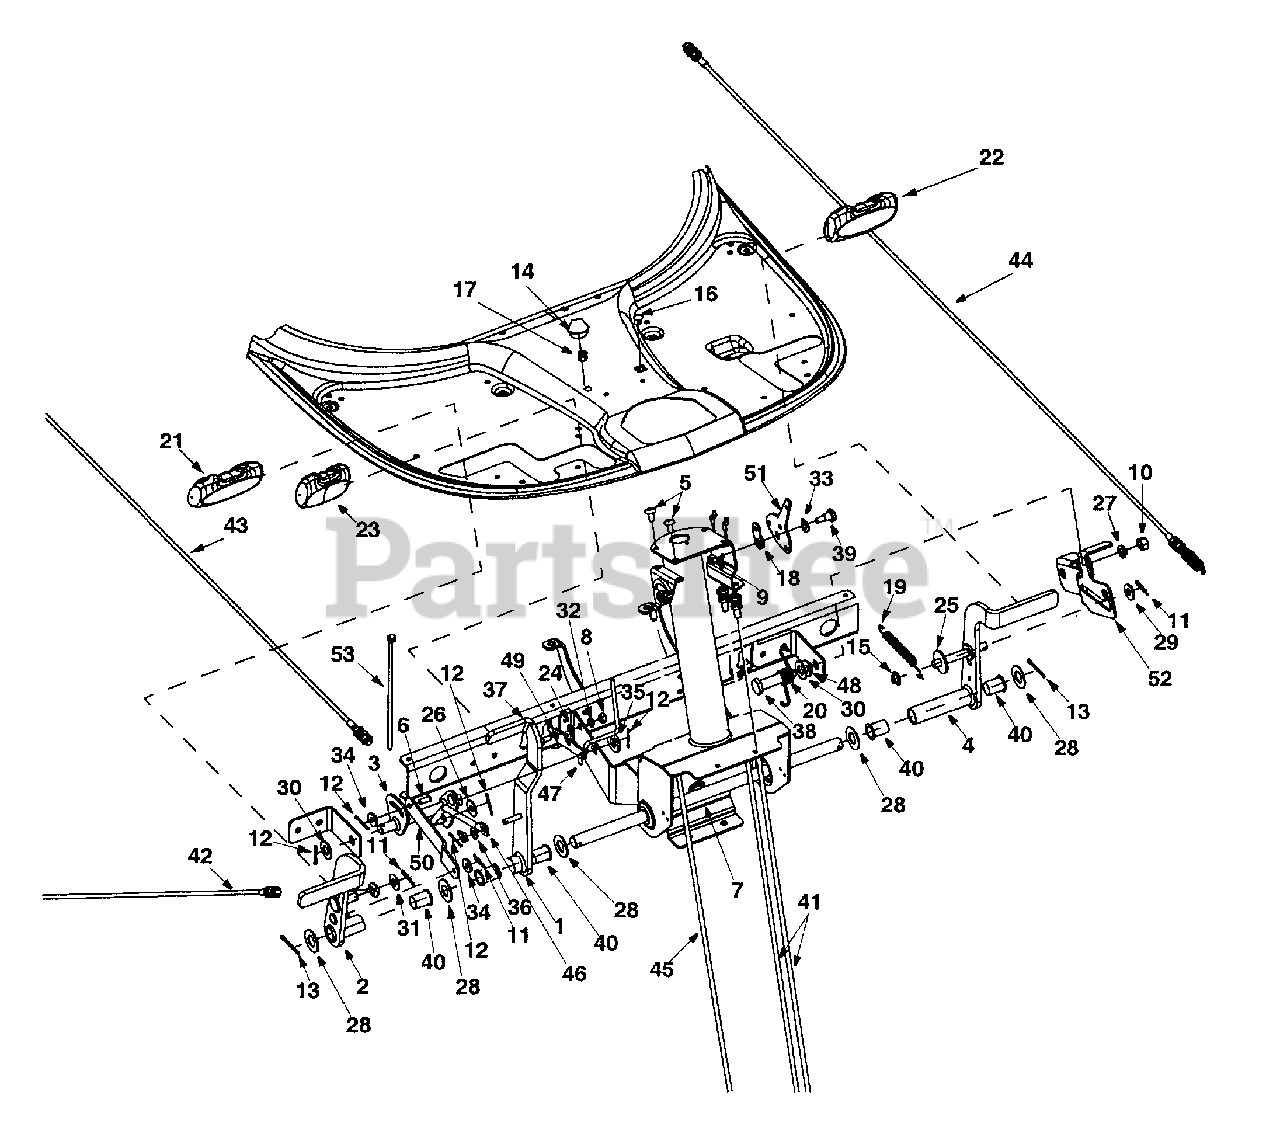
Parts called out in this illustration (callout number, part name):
6	Clevis Pin
7	Shaft
8	Hex Nut 1/4-20
9	Lock Nut 1/4-20
10	Hex Nut 3/8-16
11	Internal Cotter Pin
12	Hairpin Clip
13	Hairpin Clip
14	Ball Knob
15	Push Cap
16	Plug Cap
17	Snap-on Bushing
18	Stop Lever
19	Extension Spring
20	Torsion Spring
21	Drive Pad
22	Deck Pad
23	Brake Pad
24	Flat Washer 3/8 X .620 X .033
25	Flat Washer .411 x 1.25" x .100
26	5/16 Washer
27	Lock Washer
28	Flat Washer
29	Flat Washer
30	Flat Washer .510 X 1.00 X .060
31	Flat Washer
32	Lock Washer
33	Spring Washer
34	Flat Washer
35	Flat Washer .531 X 1.062 X .134
36	Flat Washer .271 X .630 X .065
37	Shoulder Screw .375 Dia X .18
38	Shoulder Screw
39	Shoulder Screw .375 X .380 X 1/4-20
40	Flange Bearing
41	Shift Cable
42	Variable Drive Cable
43	Brake Cable
44	Deck Cable
45	Throttle Choke Cable: 67"
46	Brake Rod
47	Brake Lock Out Rod
48	Shoulder Spacer
